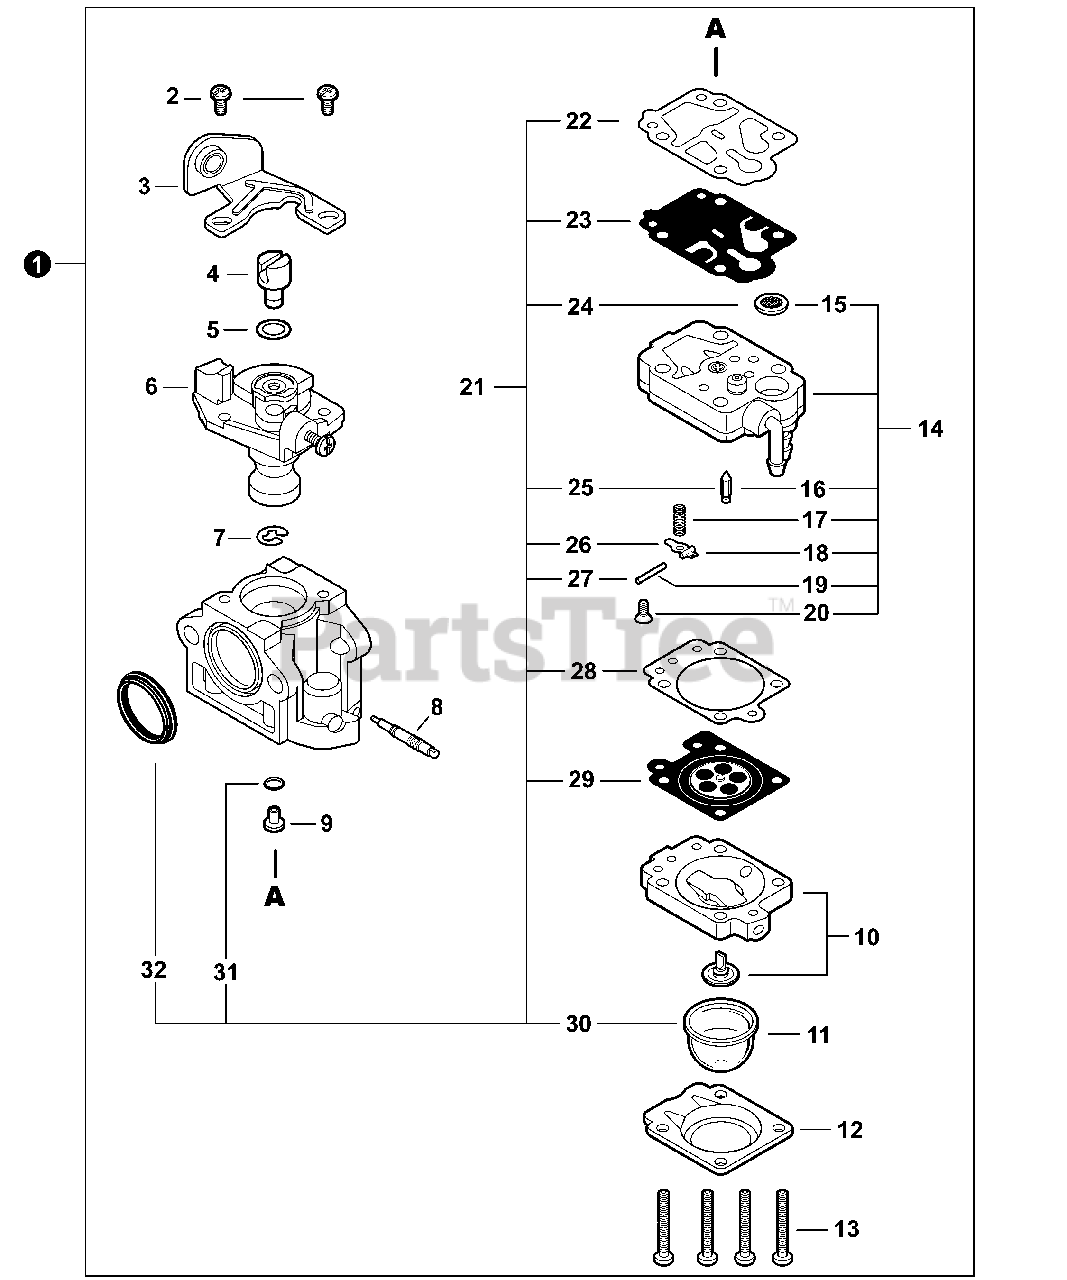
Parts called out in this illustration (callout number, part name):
1	CARBURETOR - WYK-353
3	BRACKET, THROTTLE CABLE
6	VALVE ASSY, THROTTLE
8	NEEDLE, HIGH SPEED
9	JET, MAIN #31
10	BODY ASSY, PURGE
11	BULB, PURGE
12	RETAINER, PURGE BULB
14	BODY ASSY, PUMP
15	SCREEN, FUEL INLET
16	VALVE, INLET NEEDLE
17	SPRING, METERING LEVER
18	LEVER, METERING
19	PIN, METERING LEVER
20	SCREW
21	REPAIR KIT, CARBURETOR
22	GASKET, PUMP
23	DIAPHRAGM, PUMP
24	SCREEN, FUEL INLET
25	VALVE, INLET NEEDLE
26	LEVER, METERING
27	PIN, METERING LEVER
28	GASKET, METERING DIAPHRAGM
29	DIAPHRAGM, METERING
30	BULB, PURGE
31	O-RING
32	RING, PACKING
